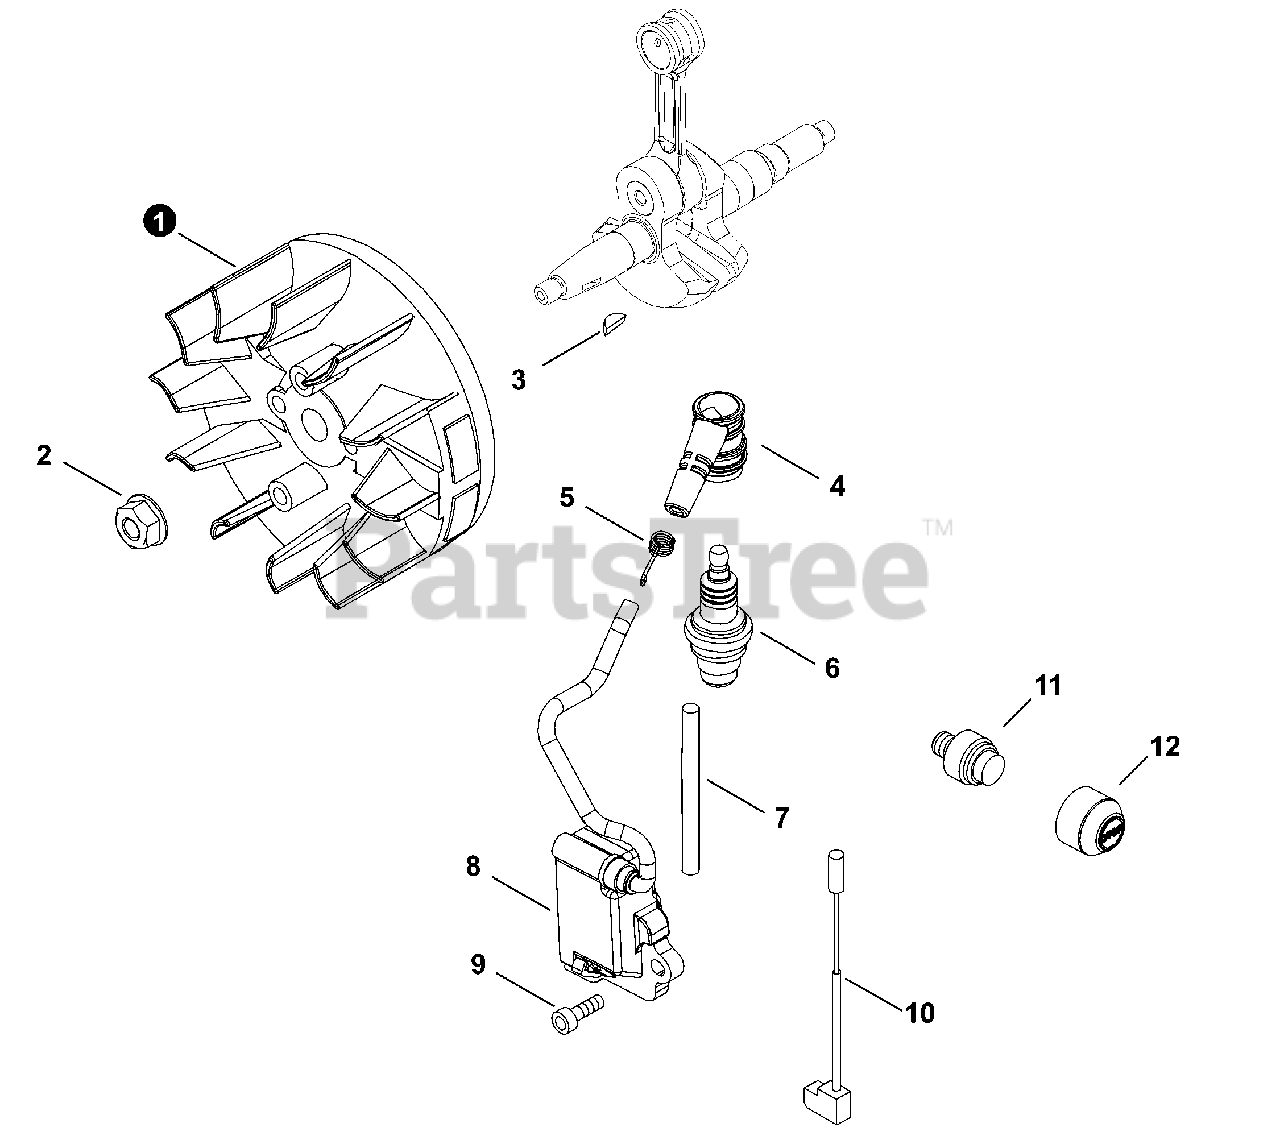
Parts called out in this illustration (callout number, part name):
1	FLYWHEEL
2	NUT M8×1.0
3	KEY, WOODRUFF 3×10
4	CAP, SPARK PLUG
5	TERMINAL, SPARK PLUG
6	SPARK PLUG - BPMR7A
7	TUBE, INSULATOR
8	COIL, IGNITION
11	SWITCH, ON-OFF
12	CAP, SWITCH
